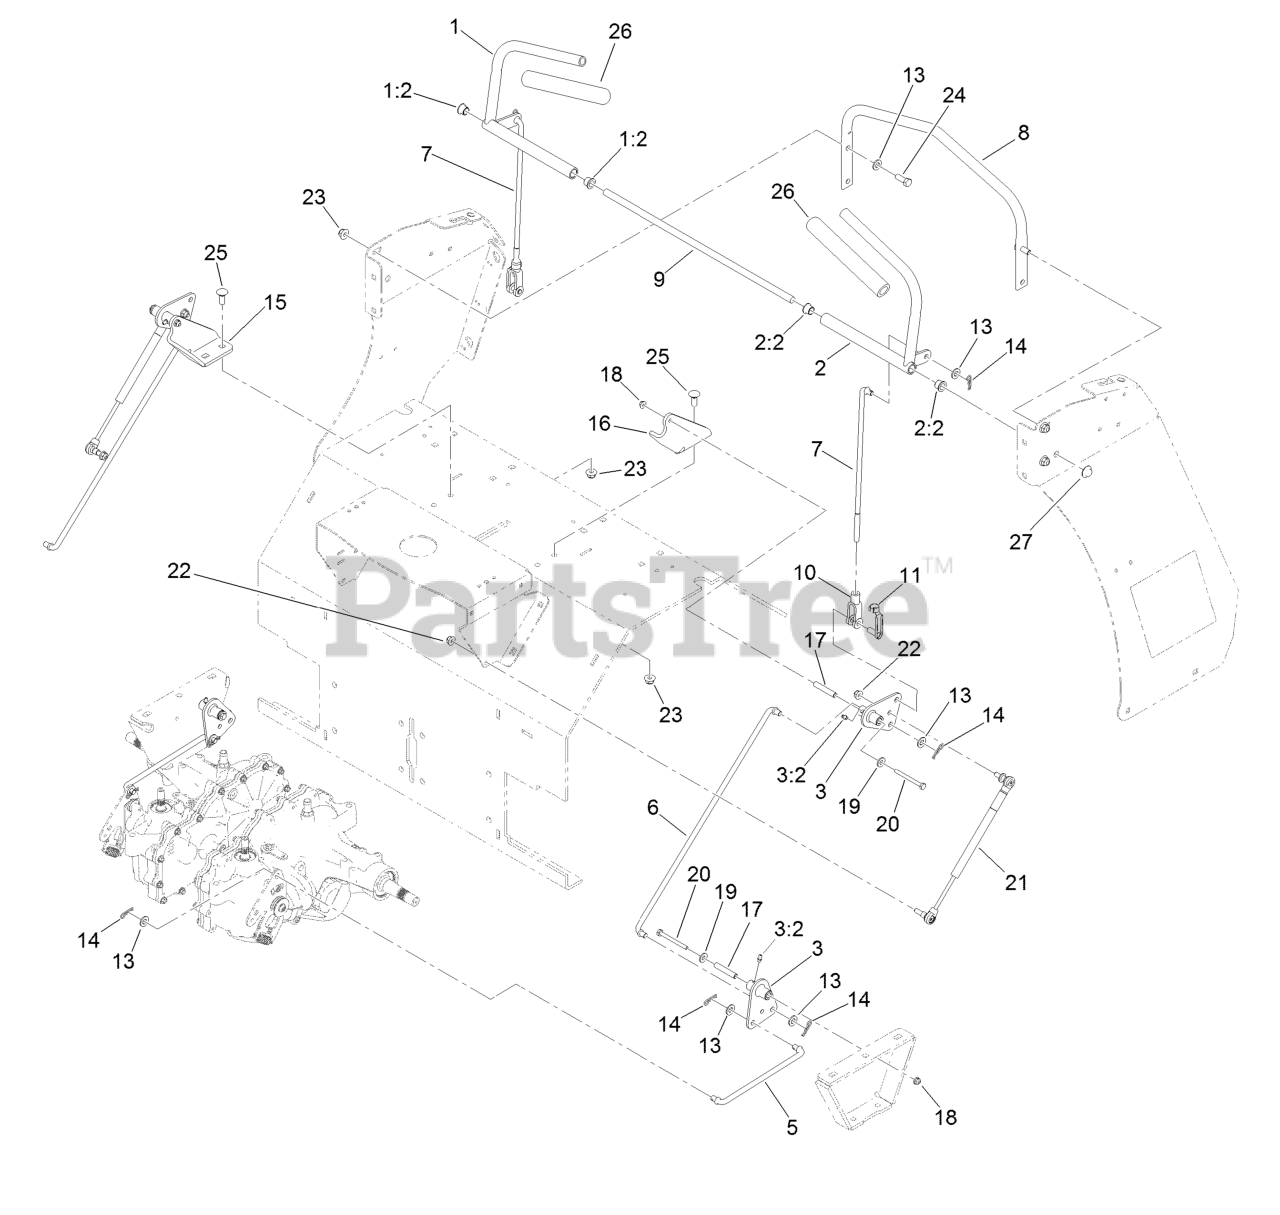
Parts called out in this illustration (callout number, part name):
1	RH Control Handle ASM
1:2	Bearing-Flange
2	LH Control Handle ASM
2:2	Bearing-Flange
3	Crank-Bell
3:2	Fitting-Grease
5	Link-Control, Hydro
6	Link-Control, Bell Crank
7	Link-Control, Bell Crank
8	Bar-Reference
9	Shaft-Pivot, Control
10	Yoke-Linkage, Brake
11	Pin-Spring, Clevis
13	Washer-Flat
14	Pin-Cotter
15	Bracket-Pivot, RH
16	Bracket-Pivot, LH
19	Washer-Flat
20	Screw-HH
21	Damper-Control, Motion
22	Nut-HF, NI
23	Nut-HF, NI
24	Screw-HH
25	Bolt-CARR
26	Grip-Lever, Control
27	Nut-Push
